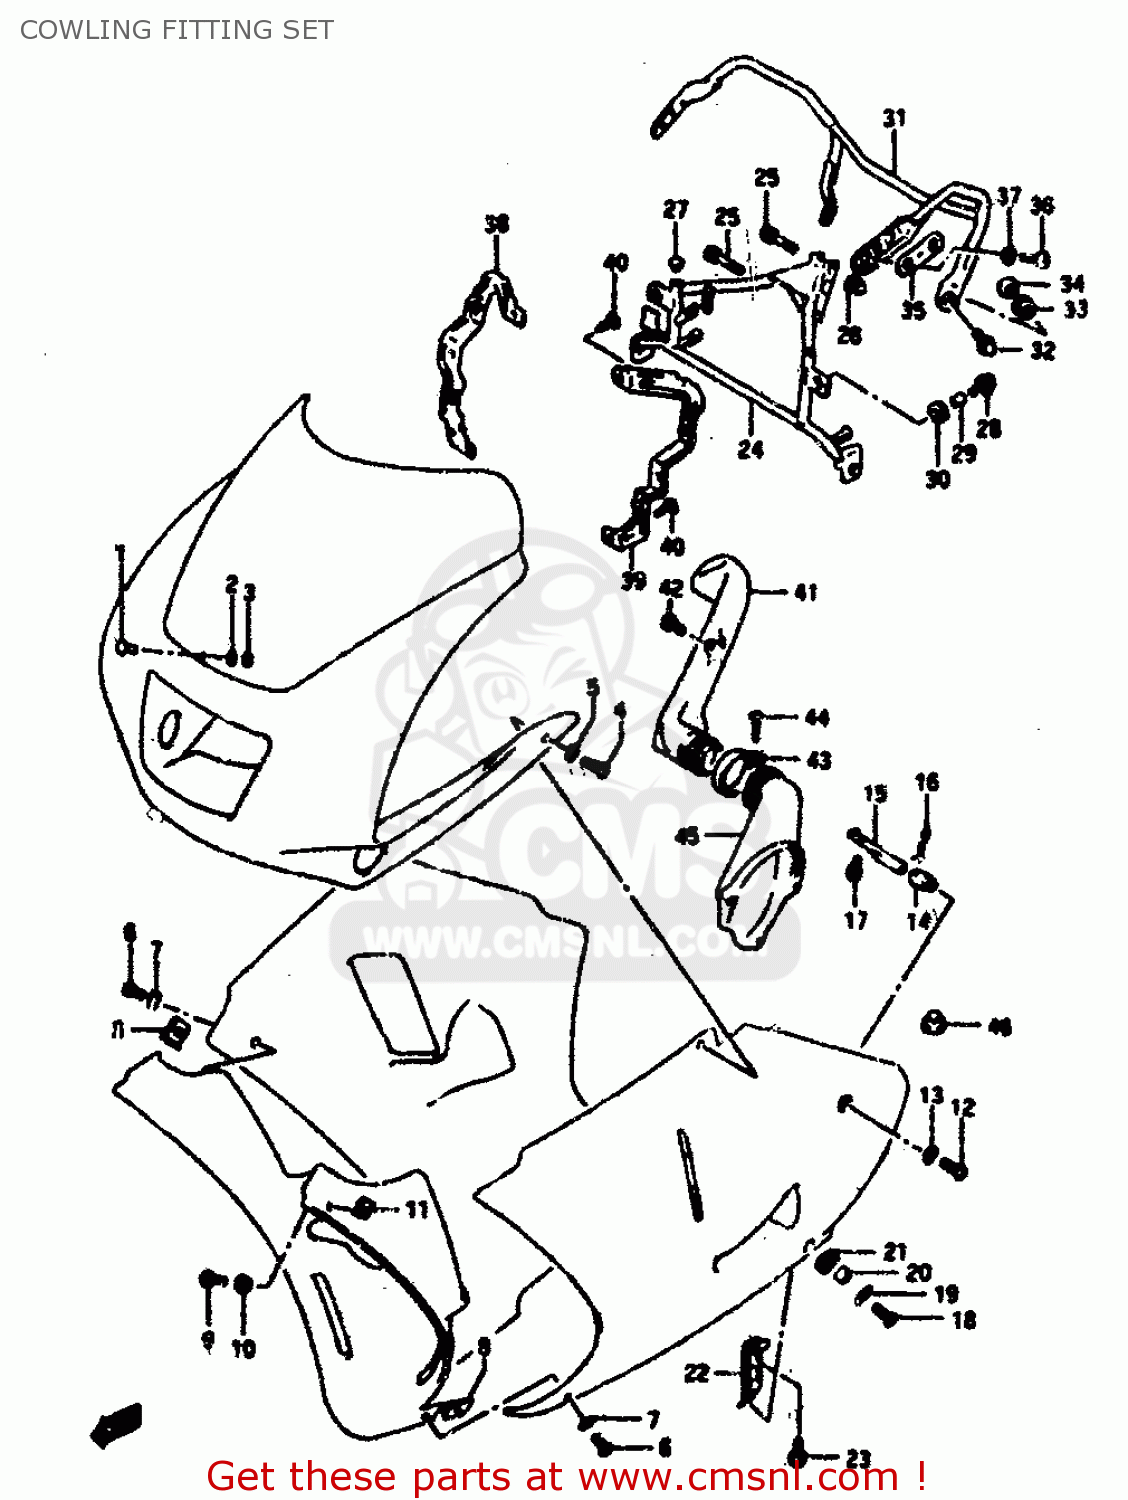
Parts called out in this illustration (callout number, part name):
1	PIN,WINDSCREEN
2	CUSHION
3	NUT
4	SCREW(5X16)
5	WASHER(7X13X0.6)
6	SCREW(5X16)
7	WASHER(7X13X0.6)
8	NUT,RH & CTR UNDER COWLING
9	SCREW
10	WASHER(5.2X14X1.5)
11	NUT
12	SCREW(6X18)
13	WASHER
14	PLUG,UNDER COWL FTG,CTR
15	PIPE,UNDER COWL FTG CTR
16	PIN,UNDER COWLING FITTING PIPE
17	BOLT
18	SCREW(6X18)
19	WASHER(6.5X18X1)
20	SPACER (6.1X9X10)
21	CUSHION
22	BRACKET, UNDER LH
23	BOLT
24	BRACE,COWL
25	BOLT
26	NUT ,8MM
27	CAP(OD:12)
28	BOLT 6X20
29	SPACER (6.1X9X10)
30	CUSHION
31	BRACE, REAR VIEW MIRROR
32	BOLT 6X20
33	CUSHION
34	WASHER
35	CUSHION,RR VIEW MIRRORR
36	SCREW(6X12)
37	WASHER(6.2X19X1.5)
38	BRACKET,HEADLAMP FIT,R
39	BRACKET,HEADLAMP FIT,L
40	SCREW
41	BODY,AIR DUCT COWL NO.1
42	SCREW, FRONT & REAR
43	CLAMP
44	SCREW 4X25
45	BODY,AIR DUCT COWL NO.2
46	CUSHION
